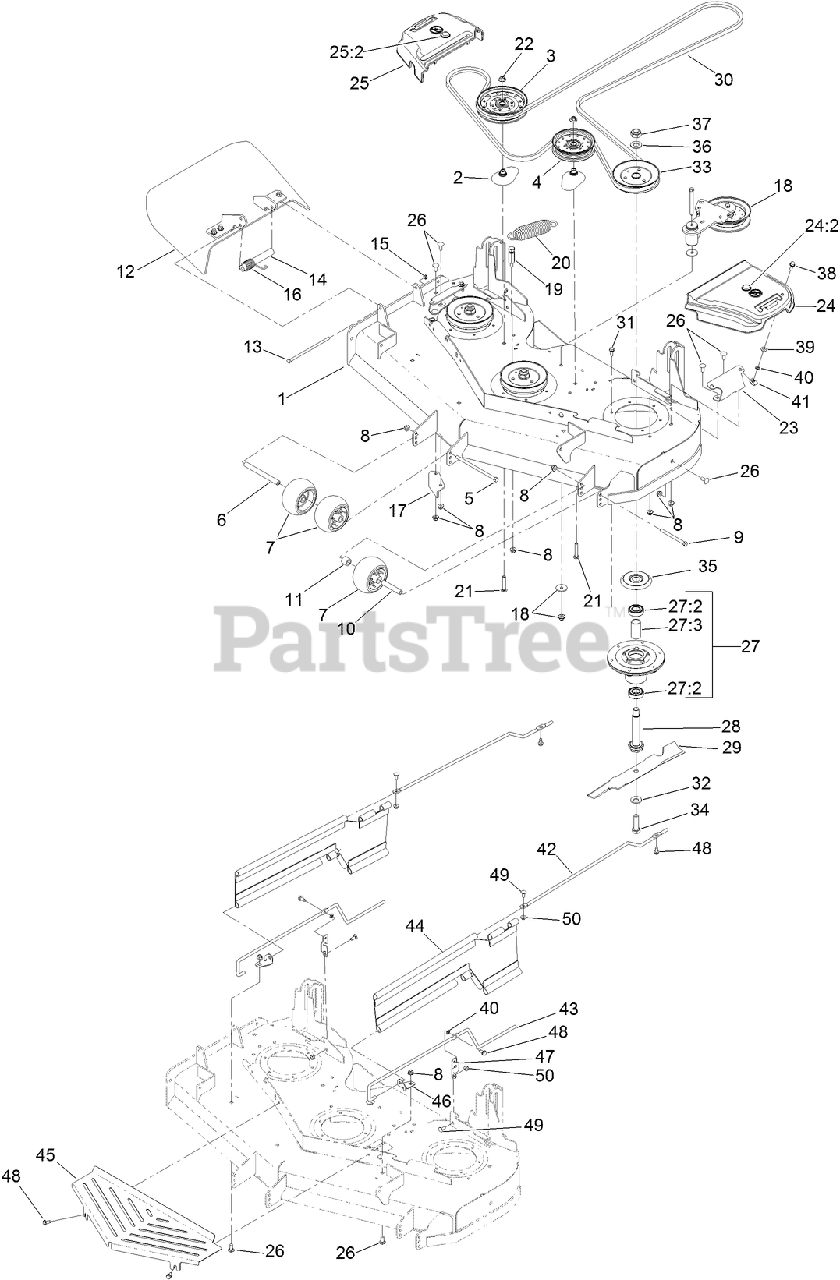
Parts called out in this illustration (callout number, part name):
1	DECK ASM
2	SPACER-PULLEY
3	PULLEY-IDLER, FLAT
4	PULLEY-IDLER, FLAT
5	SCREW-HH
6	SPACER-WHEEL
7	ROLLER-SCALP, ANTI
8	NUT-HF, NI
9	SCREW-HH
10	TUBE-SPANNER
11	TUBE-SPACER
12	DEFLECTOR ASM
13	SCREW-HH
14	SPACER
15	NUT-LOCK, NI
16	SPRING-TORSION
17	BAFFLE-DISCHARGE
18	IDLER ARM ASM
19	ANCHOR-SPRING, TALL
20	SPRING-EXTENSION
21	BOLT-CARR, SHORT NECK
22	NUT-FLANGE, NI
23	BRACKET-COVER, BELT
24	LH BELT COVER ASM
24:2	PLUG-PLASTIC
25	RH BELT COVER ASM
25:2	PLUG-PLASTIC
26	SCREW-CARR
27	SPINDLE ASM
27:2	BEARING-BALL
27:3	SPACER-BEARING
28	SPINDLE-SHAFT
29	BLADE-HI FLO, 16.50 INCH
30	BELT-V
31	SCREW-TAPTITE
32	WASHER-BELLEVILLE
33	PULLEY-B SECTION
34	SCREW-BLADE
35	SHIELD-BEARING
36	WASHER
37	NUT-LOCK, NI
38	SCREW-HHF
39	WASHER-THRUST
40	NUT-PUSH
41	NUT-U
42	ROD-SUPPORT, UPPER
43	ROD-SUPPORT, LOWER
44	GUARD-SIDE
45	SHIELD-FRONT
46	BRACKET-SUPPORT, FRONT ROD
47	BRACKET-MOUNTING, REAR
48	SCREW-HWHTF
49	SCREW-CARR
50	NUT-HF, NI
